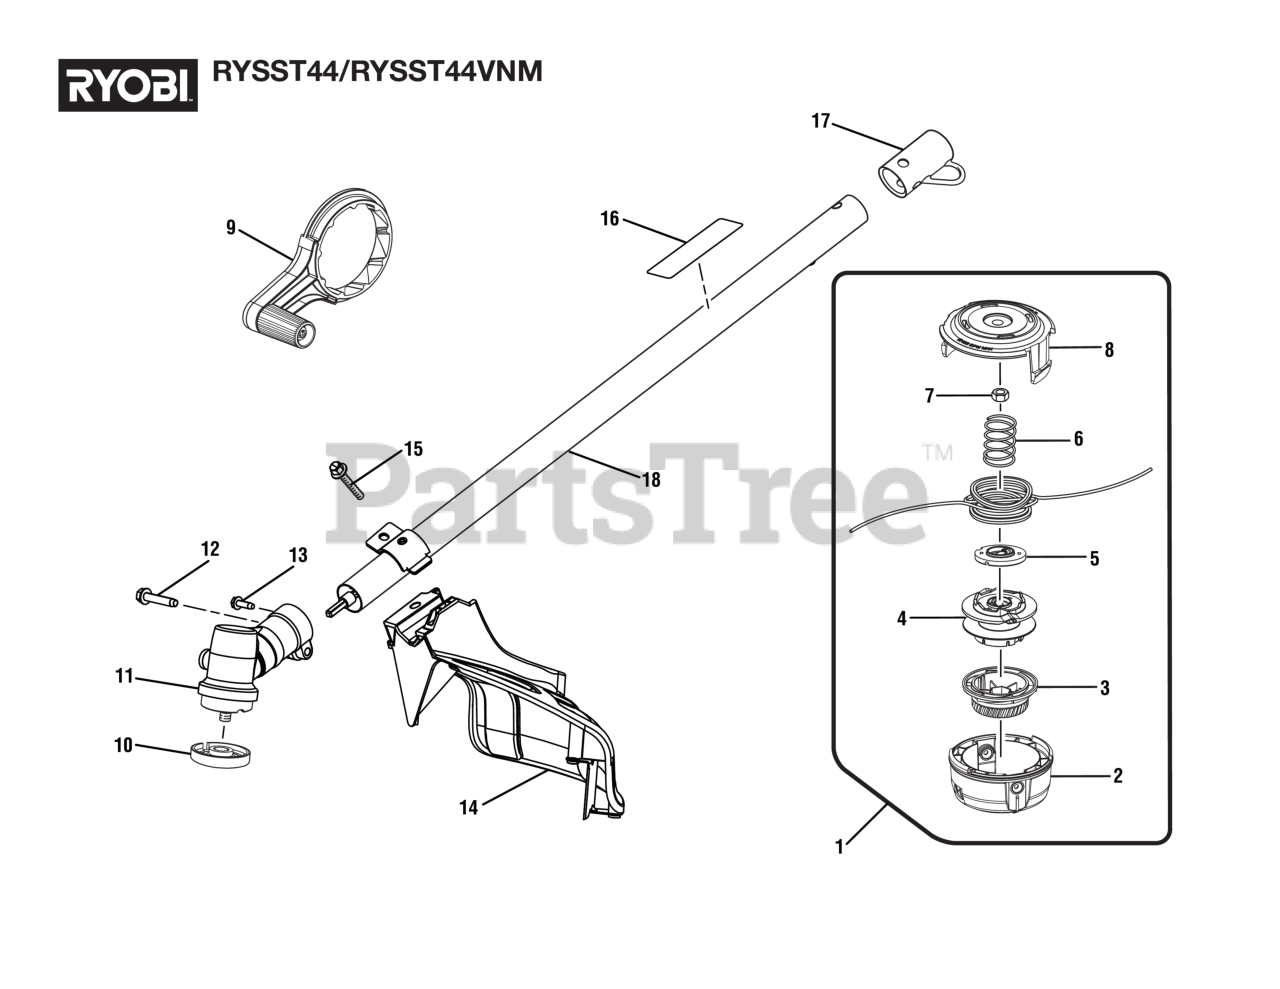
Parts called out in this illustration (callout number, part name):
1	ARBORLESS, RYOBI SS ATTACHMENT
2	Lower Housing
3	Bump Knob (Green)
4	Spool Assembly
5	String Guide
6	Compression Spring
7	Hex Nut (M8, Left Hand Threads)
8	Upper Housing
9	Crank Handle Assembly
10	FLANGED WASHER
11	Gear Case Assembly
12	Screw (1/4-20 x 1-1/4 in., Hex Washer Hd. S.T.)
13	Screw w/Washer (10-24 x 5/8 in., Hex Hd. T.F.)
14	Grass Deflector Assembly
15	SCREW (#1/4-20 X 1-1/4 in. HEX WASHER HD.)
16	Warning Icon Label
17	Storage Hanger Cap
18	Straight Shaft Assembly
